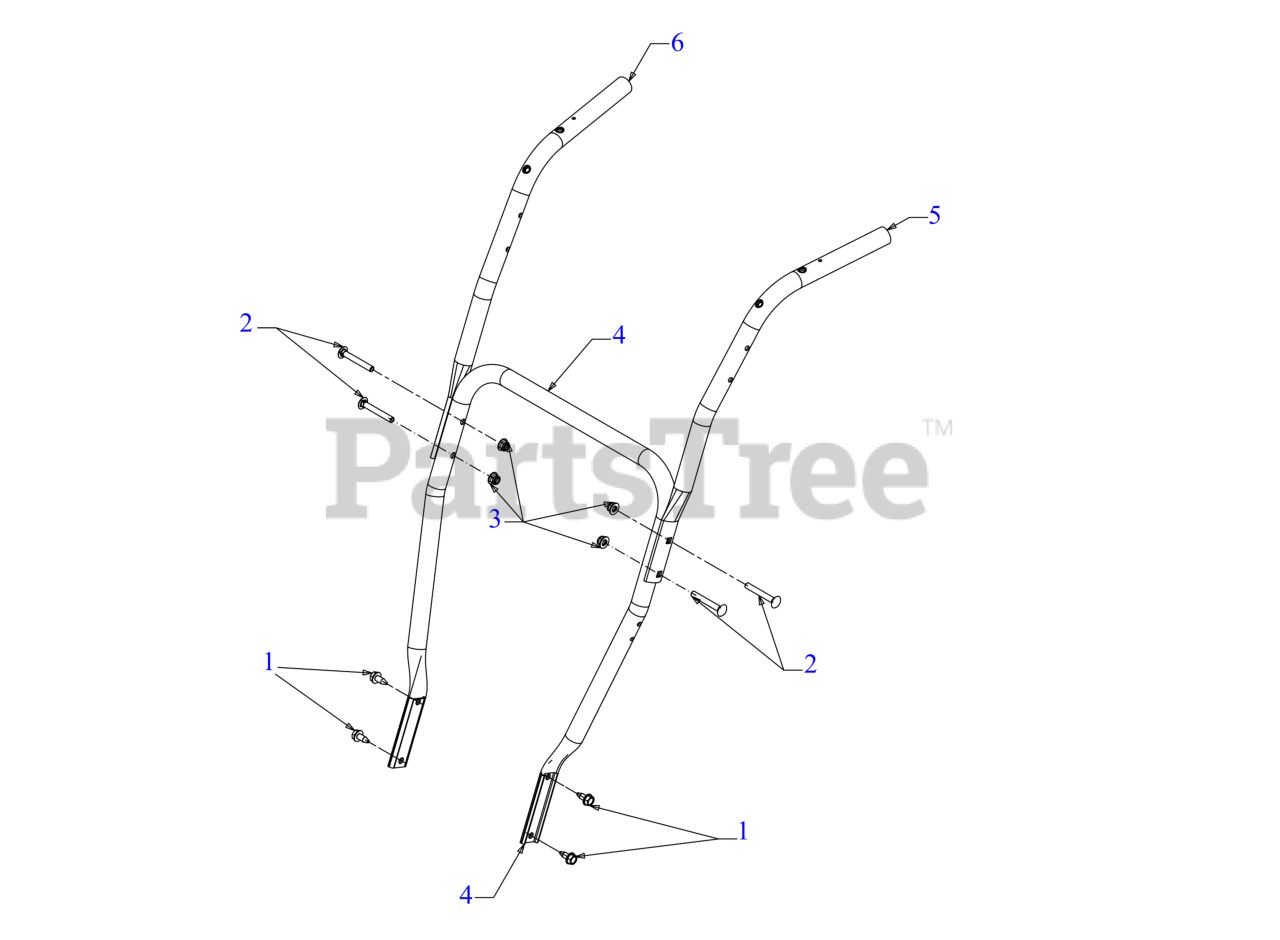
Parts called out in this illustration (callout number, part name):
1	SCREW 5/16-18 x .750
2	BOLT 5/16-18 x 2.50 GR1
3	FLANGE LOCK NUT 5/16-18
5	UPPER HANDLE (LH)
6	UPPER HANDLE (RH)
